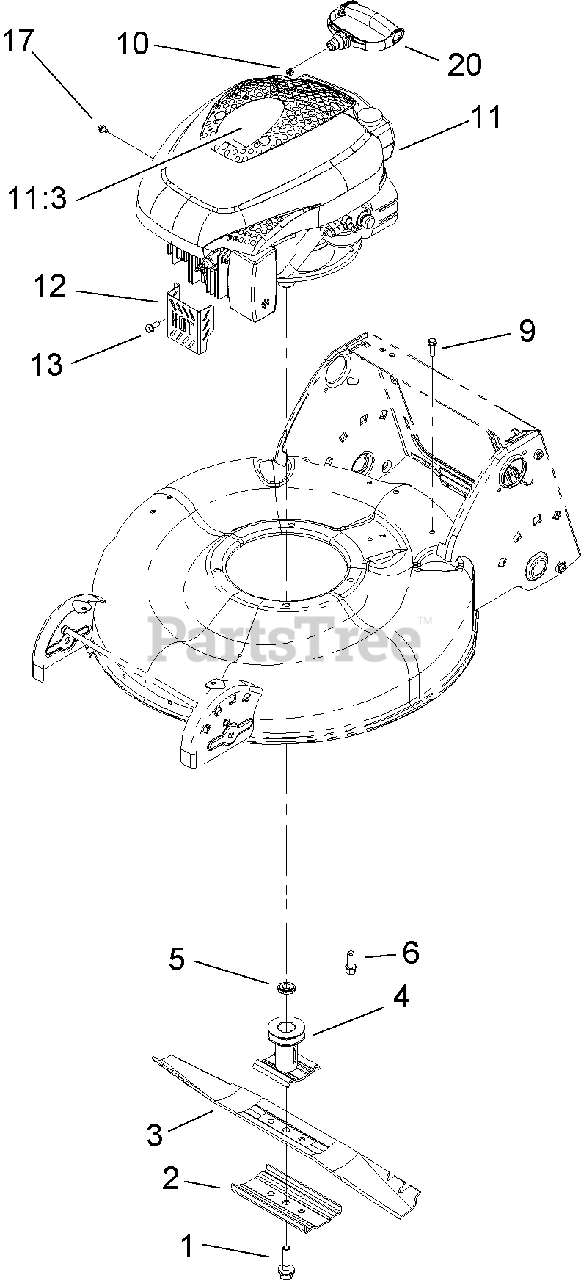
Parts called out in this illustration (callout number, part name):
1	BOLT-BLADE
2	SUPPORT-BLADE
3	BLADE-21 INCH
4	BLADE DRIVER ASM
5	Spacer-Driver
6	SCREW
9	SCREW-HWH
10	STOP-ROPE
11:3	DECAL-RECOIL
12	GUARD-MUFFLER
13	SCREW-HWH
17	SCREW-HWH
20	HANDLE-RECOIL
